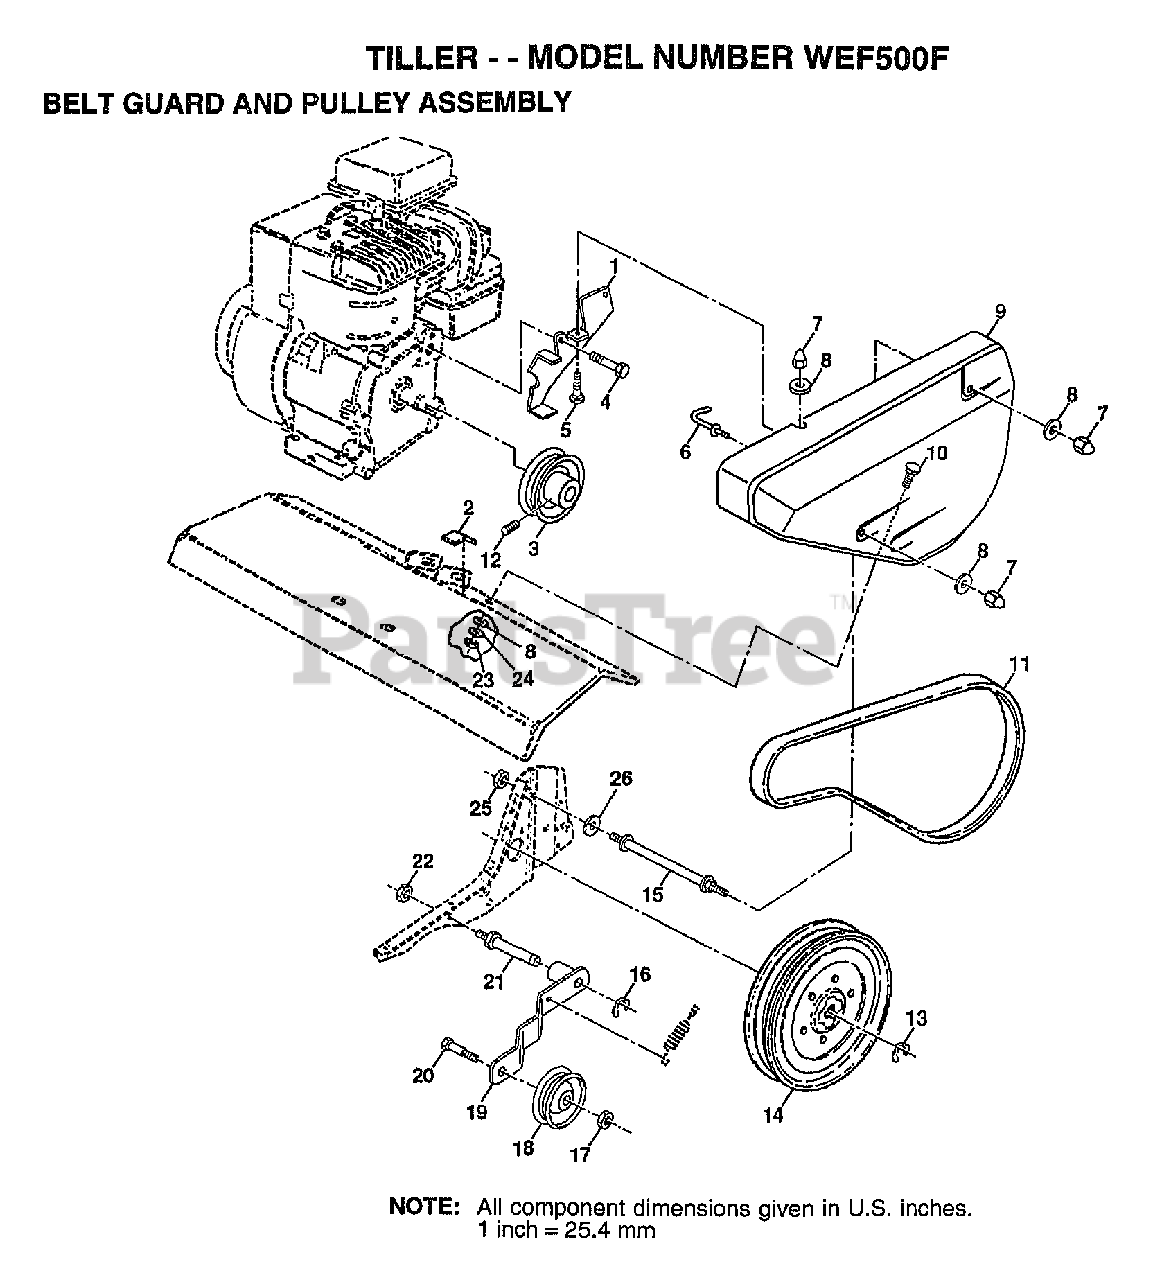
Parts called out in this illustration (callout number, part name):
1	BRKT GUARD BELT
2	PAD IDLER TI
3	ENGINE PULLEY
4	BOLT.HEX.HEAD
5	BOLT
7	NUT-CAP TI
8	WASHER
9	GUARD.PNT.BELT
10	BOLT T
11	V BELT STD
12	SET SCREW
14	SHEAVE.TRANS
15	BOLT TI
16	KLIP RING TI
17	NUT
18	"PULLEY,IDLER"
19	"ARM, IDLER"
21	SHAFT IDLER TI
22	JAM NUT TI
24	LOCKWASHER
25	NUT
26	WASHER
